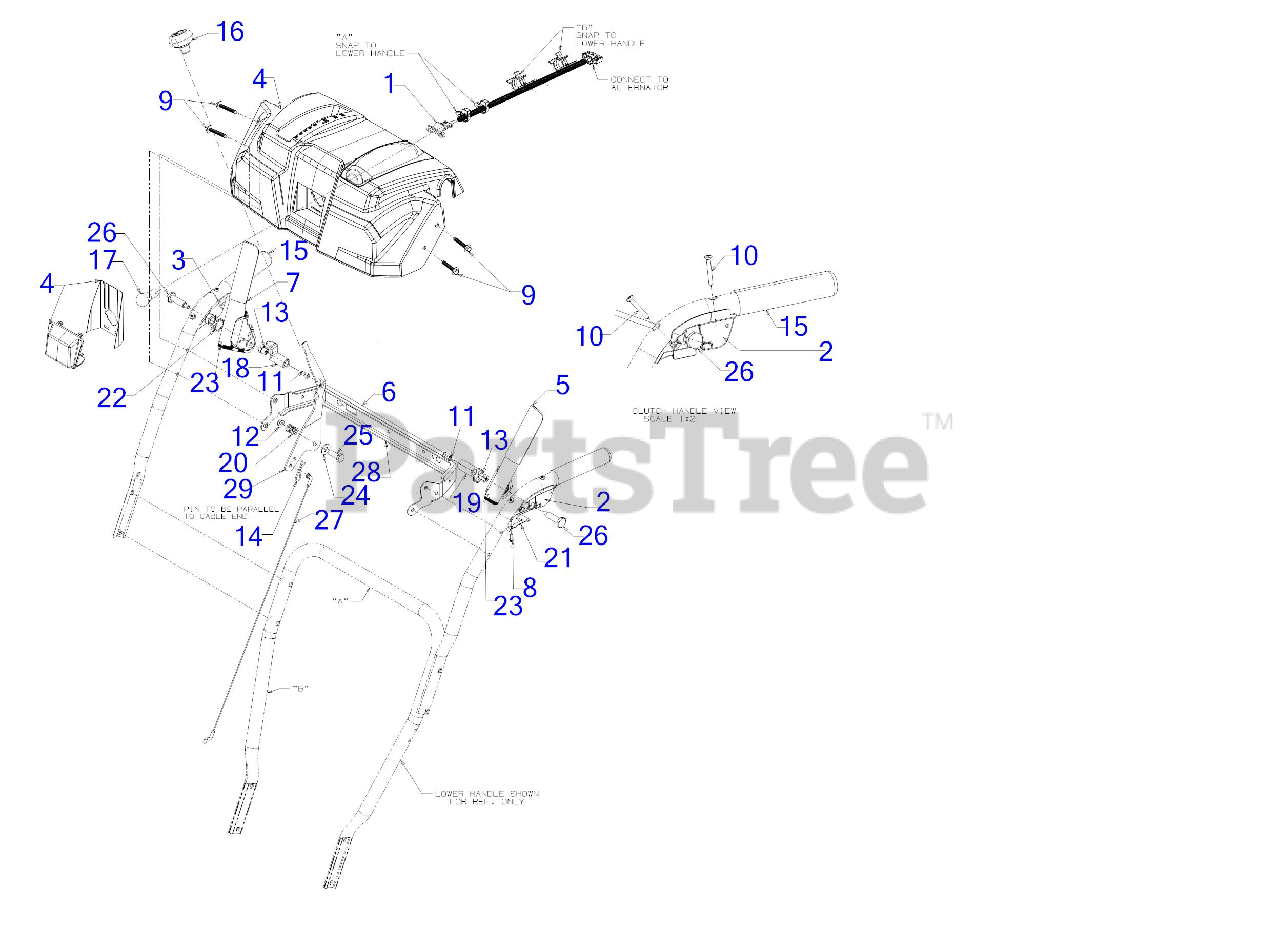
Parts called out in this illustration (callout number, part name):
1	HEADLIGHT SOCKET
1	LIGHT HARNESS
2	CLUTCH LOCK HANDLE ASSEMBLY (LH)
3	CLUTCH LOCK HANDLE ASSEMBLY (RH)
4	HANDLE PANEL
5	HANDLE ASSEMBLY (LH)
7	ENGAGEMENT HANDLE ASSEMBLY (RH) (BLACK)
8	SCREW #8-16 x .50
9	SCREW 1/4-20 x 1.625
10	SCREW #10-24 x 1.375
11	SCREW 1/4-20 x .50
12	FLANGE LOCK NUT
13	HEX NUT W/PATCH
14	INTERNAL COTTER PIN
16	SHIFT KNOB
17	LAMP-#1683
19	CLUTCH LOCK CAM
20	COMPRESSION SPRING
21	CLUTCH SPRING
22	TORSION SPRING
23	RUBBER BUMPER
24	FLAT WASHER
25	SHOULDER SCREW
26	SHOULDER SCREW .437 x 1.345 1/4-20
27	SPEED SELECTOR CABLE (PLASTIC)
